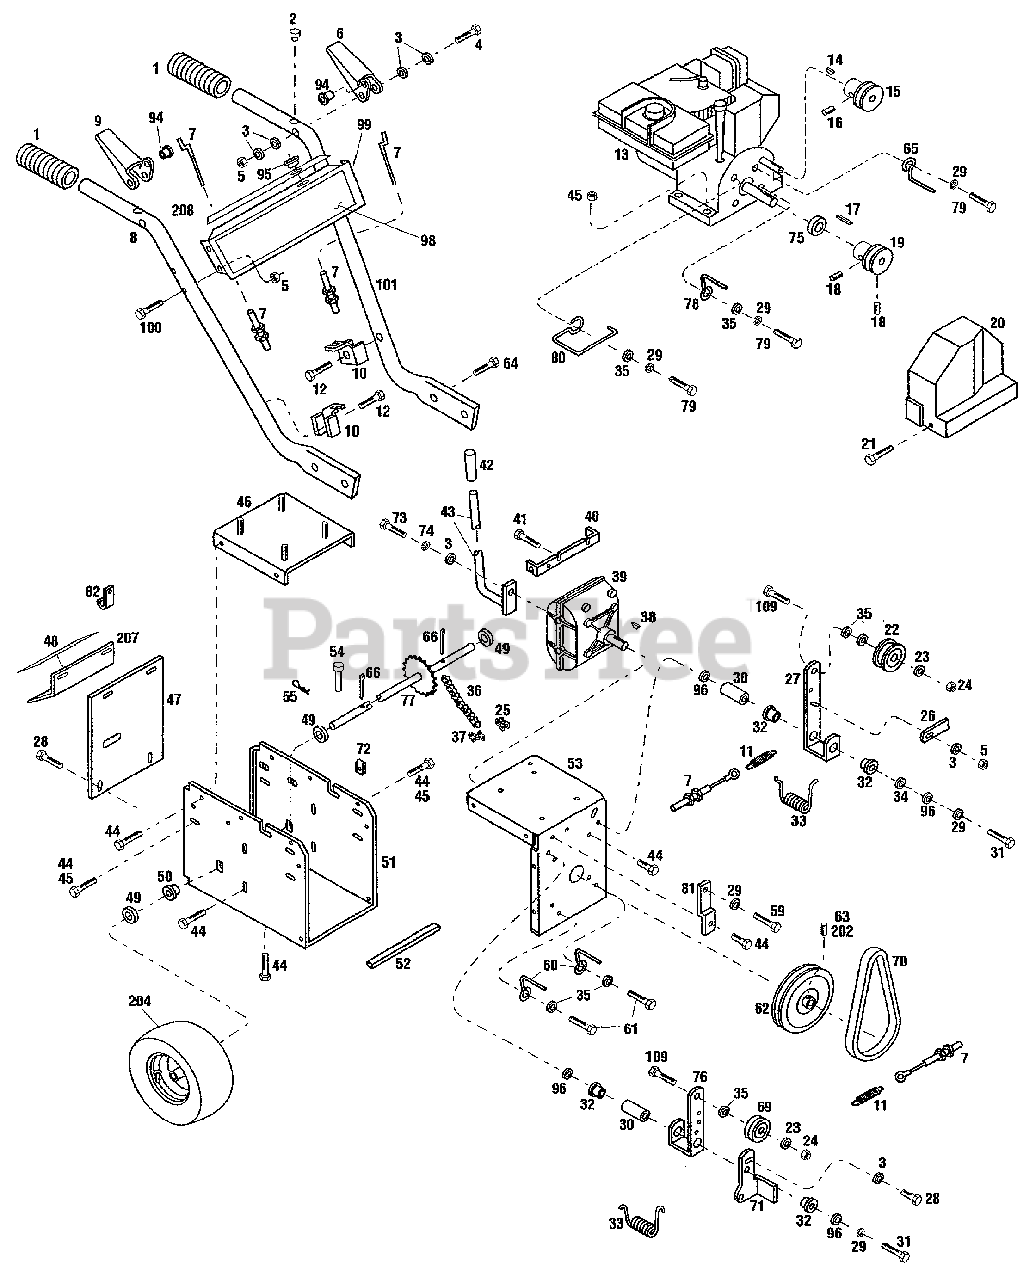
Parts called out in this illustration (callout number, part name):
1	Handle Grip
2	Bumper
3	Flat Washer, 1/4
4	Hex hd. Screw, 1/4-20 x 1-3/4
5	Locknut, 1/4-20
6	Control Lever
7	Drive Cable
8	Handlebar - right hand
9	Control Lever
10	Cable Bracket
11	Extension Spring
12	Thread Forming Screw, 1/4-20 x 3/4
14	Woodruff Key, 1/8 x 5/8
15	PTO Sheave
16	Set Screw, 1/4-20 x 3/8
17	Square Key, 3/16 x 3/4
18	Set Screw, 5/16-18 x 5/16
19	Engine Sheave
20	Belt Cover
21	Truss Screw, #10-24 x 5/8
22	Idler Pulley
23	Lockwasher, 3/8
24	Hex Nut, 3/8-16
25	Link-Offset
26	Idler Arm Stop
27	Idler Arm
28	Thread Forming Screw, 1/4-20 x 1/2
29	Lockwasher, 5/16
30	Spacer
31	Hex hd. Screw, 5/16-18 x 2-1/2
32	Bearing - Nyliner
33	Torsion Spring
34	Flat Washer, 1/2
35	Flat Washer, 5/16
36	Drive Chain #41
37	Connector Link
38	Hi-Pro Key, 3/16 x 3/4
39	Transmission
40	Reinforcement Bracket
41	Thread Forming Screw, 5/16-18 x 3/4
42	Handle Grip
43	Shift Handle
44	Flange Lock Screw, 5/16-18 x 1/2
45	Flange Locknut, 5/16-18
46	Doubler Plate Assembly
47	Rear Cover
48	Shift Decal
49	Flat Washer
52	Rubber Pad
53	Frame Cover
54	Clevis Pin
59	Hex hd. Screw, 5/16-24 x 5/8
60	Belt Guide
61	Hex hd. Screw, 5/16-18 x 3/4
62	Transmission Sheave
63	Set Screw, 5/16-18 x 5/8
64	Hex Flange Screw, 5/16-18 x 5/8
65	Belt Guide
66	Cotter Pin, 1/8 x 1-1/4
69	Flat Idler
70	V-Belt
71	Brake Arm
72	Speed Nut, #10
73	Hex hd. Screw, 1/4-28 x 3/4
74	Lockwasher,1/4
75	Spacer
76	Idler Arm
78	Belt Guide
79	Hex hd. Screw, 5/16-24 x 3/4
80	Belt Guide
81	Bracket
82	Cable Clamp
94	Nyliner Bearing
95	Grommet
96	Flat Washer, 1/4
98	Decal, Logo
99	Console
100	Hex hd. Screw, 1/4-20 x 1-1/2
101	Handlebar-left hand
109	Carriage Bolt, 3/8-16 x 1-3/4
200	Red Spray Paint, 13 oz. can
201	Black Spray Paint, 13 oz. can
202	Loctite #242, .02 oz.
203	Tire Chains
204	Wheel and Tire Assembly
207	Bracket, Shift Decal
208	Decal, Instructions
